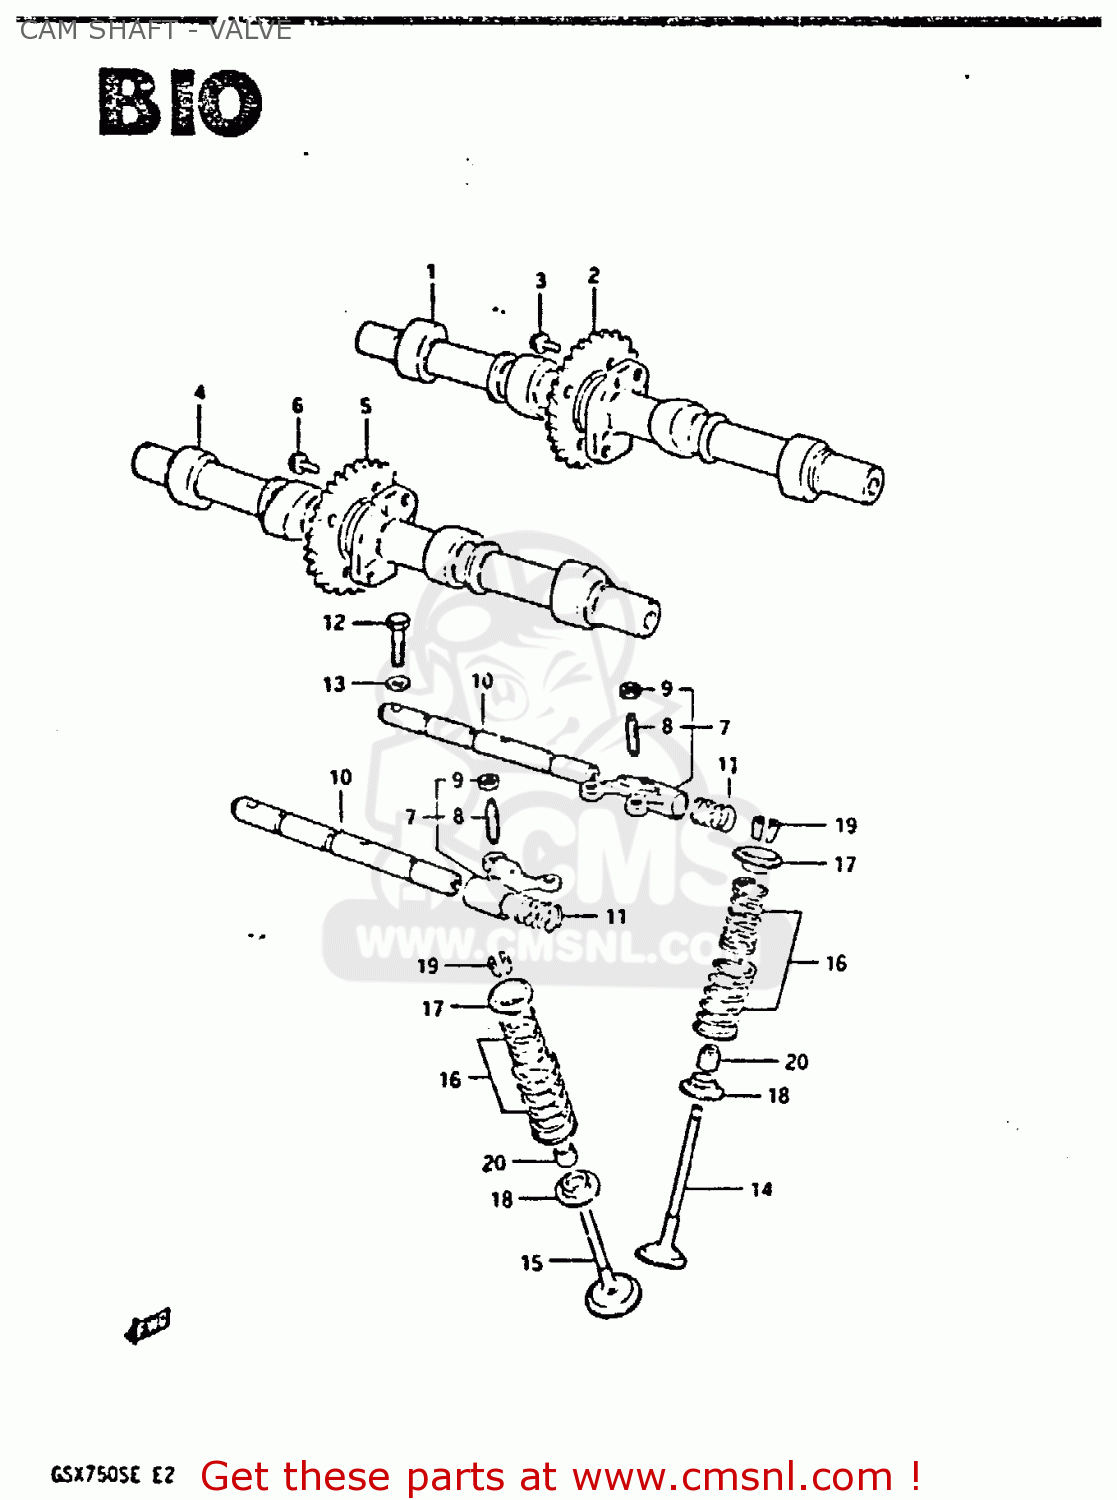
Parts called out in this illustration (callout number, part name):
1	CAMSHAFT,INTAKE
2	SPROCKET,INTAKE CAMSHAFT
3	BOLT(7X11)
4	CAMSHAFT,EXHAUST
5	SPROCKET,EXHAUST CAMSHAFT
6	BOLT(7X11)
7	ARM,VALVE ROCKER
8	SCREW,TAPPET ADJUSTING
9	NUT,ADJUSTING
10	SHAFT,VALVE ROCKER
11	SPRING
12	BOLT
13	WASHER, LOWER
14	VALVE,INTAKE
15	VALVE,EXHAUST
16	SPRING SET,VALVE
17	RETAINER,VALVE SPRING
18	SEAT,VALVE SPRING
19	COTTER VALVE
20	OIL SEAL
